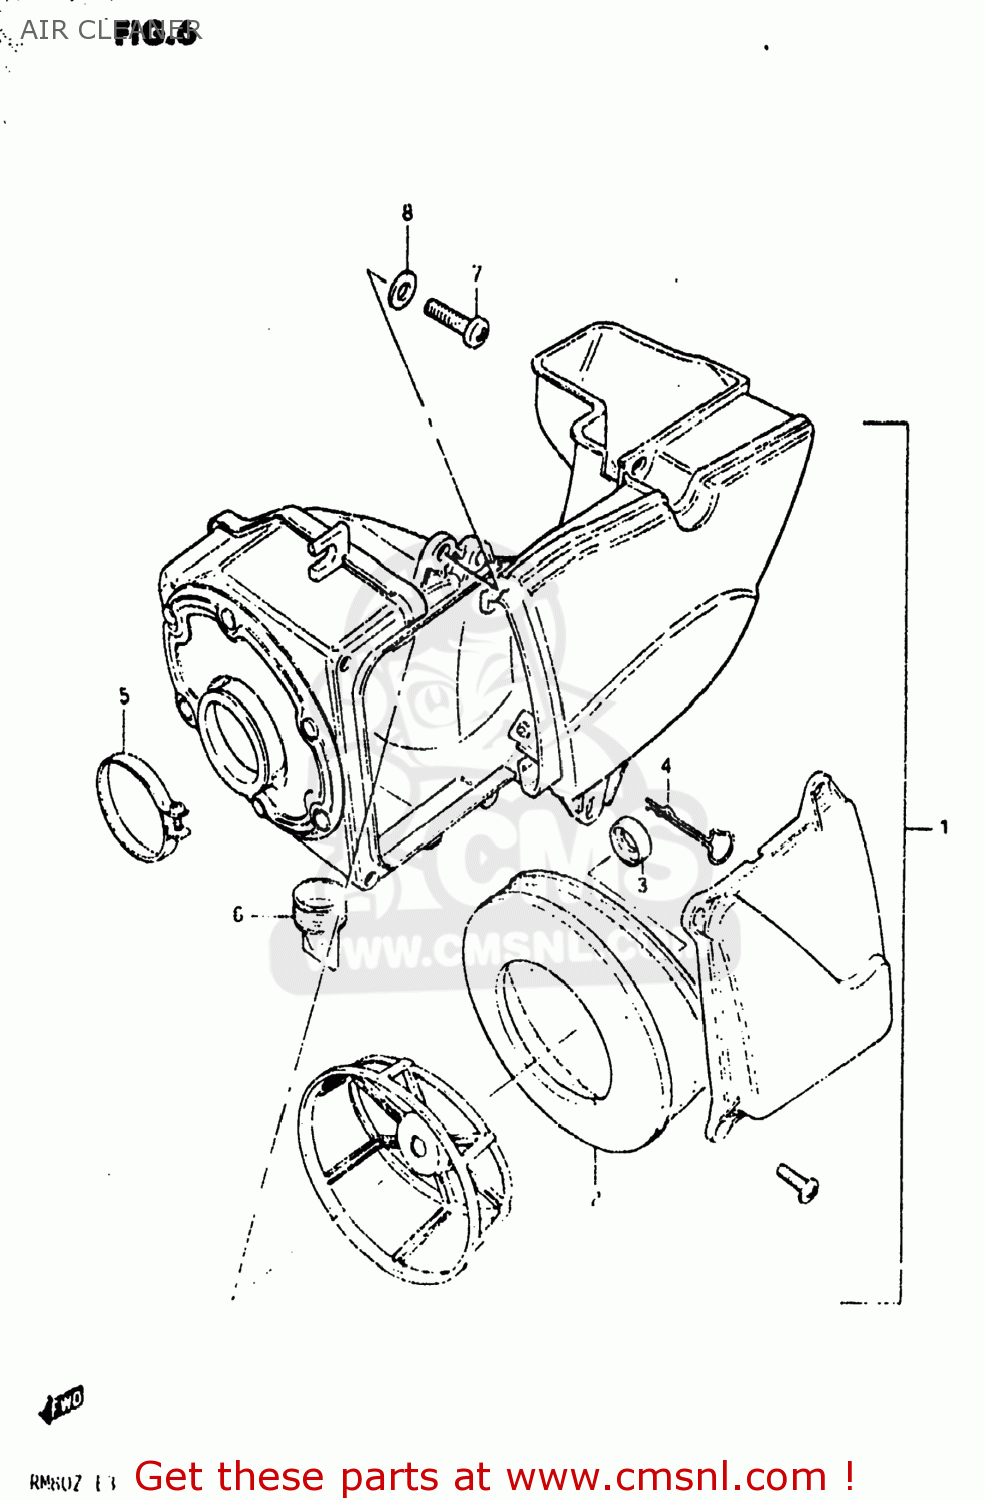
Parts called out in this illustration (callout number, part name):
1	CLEANER ASSEMBLY,AIR
2	FILTER,AIR CLEANER
3	WASHER
4	PIN,SNAP
5	CLAMP
6	HOSE,AIR CLEANER DRAIN
7	SCREW
8	WASHER
